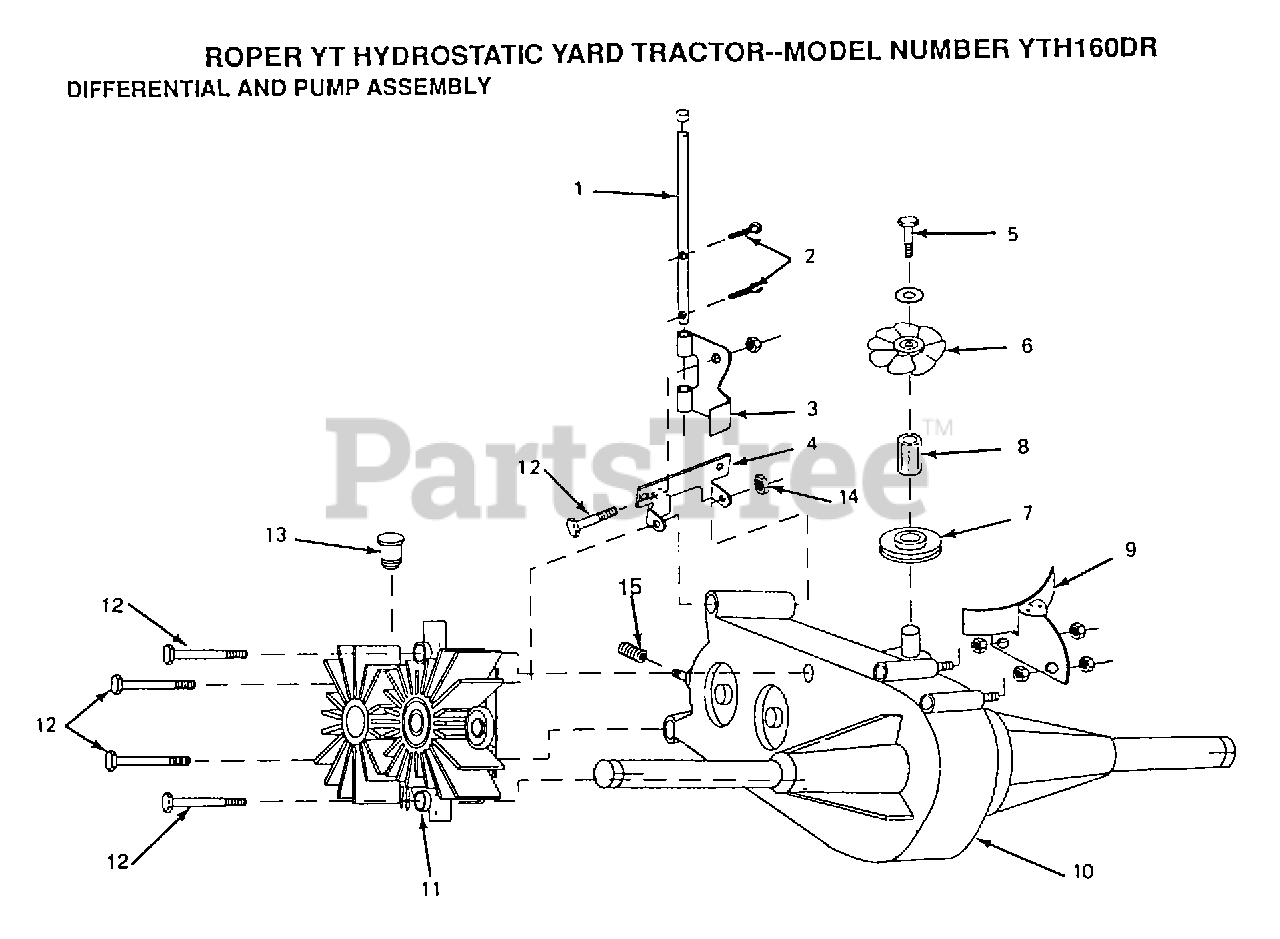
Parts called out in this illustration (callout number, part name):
4	BRACKET
5	BOLT LT
6	FAN
7	PULLEY TRANSAXLE
8	STANDOFF
9	GUARD ASSY
12	BOLT
13	PUMP.2003081.
15	SPRING
